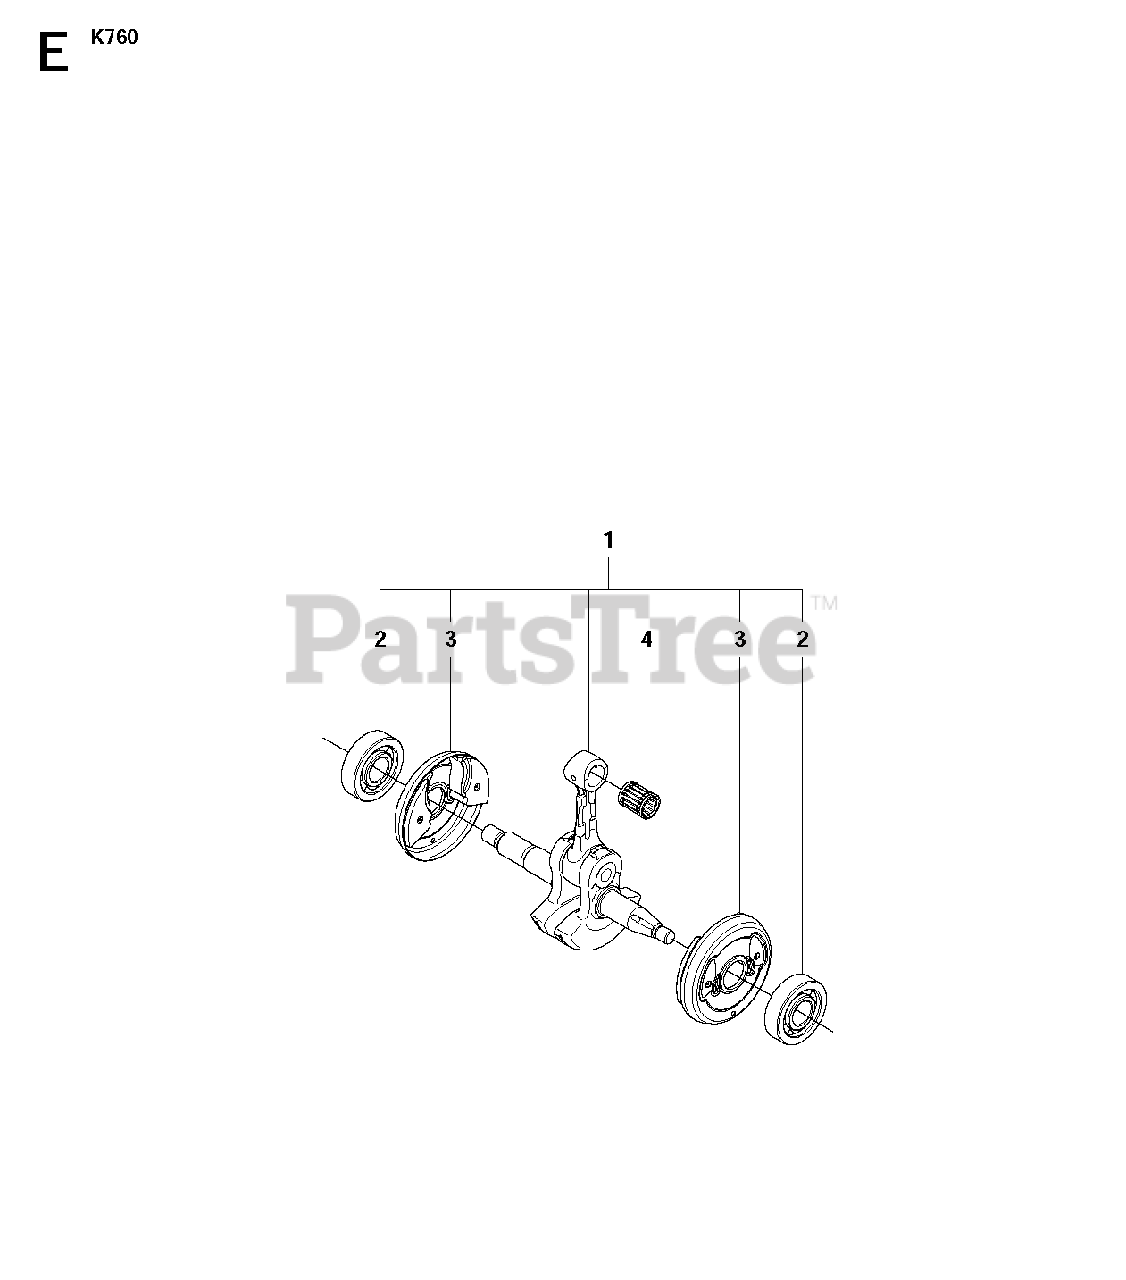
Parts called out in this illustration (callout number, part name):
1	CRANKSHAFT ASSYIncl. 2 - 4
2	BALL BEARING
4	NEEDLE BEARING
